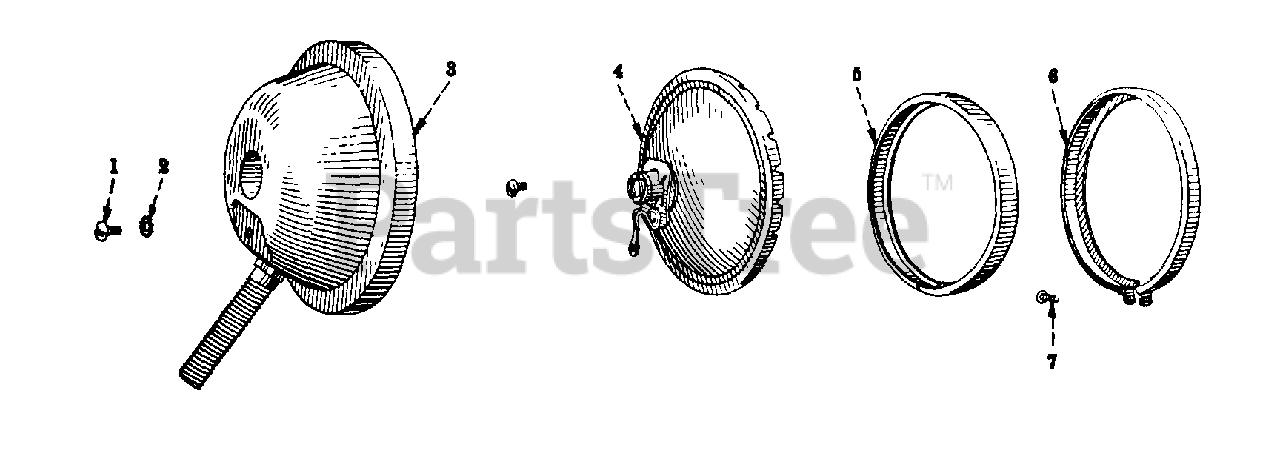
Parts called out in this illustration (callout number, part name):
1	SCREW, 8-32 NI-BRIGHT BRASS SLT-PAN-HD MACH
2	WASHER NO. 8 C-Z INT-TOOTH LOCK
3	BODY, LIGHT
4	UNIT W/SCREW 455347 AND WASHER, 135530.
7	SCREW, MOULDING
